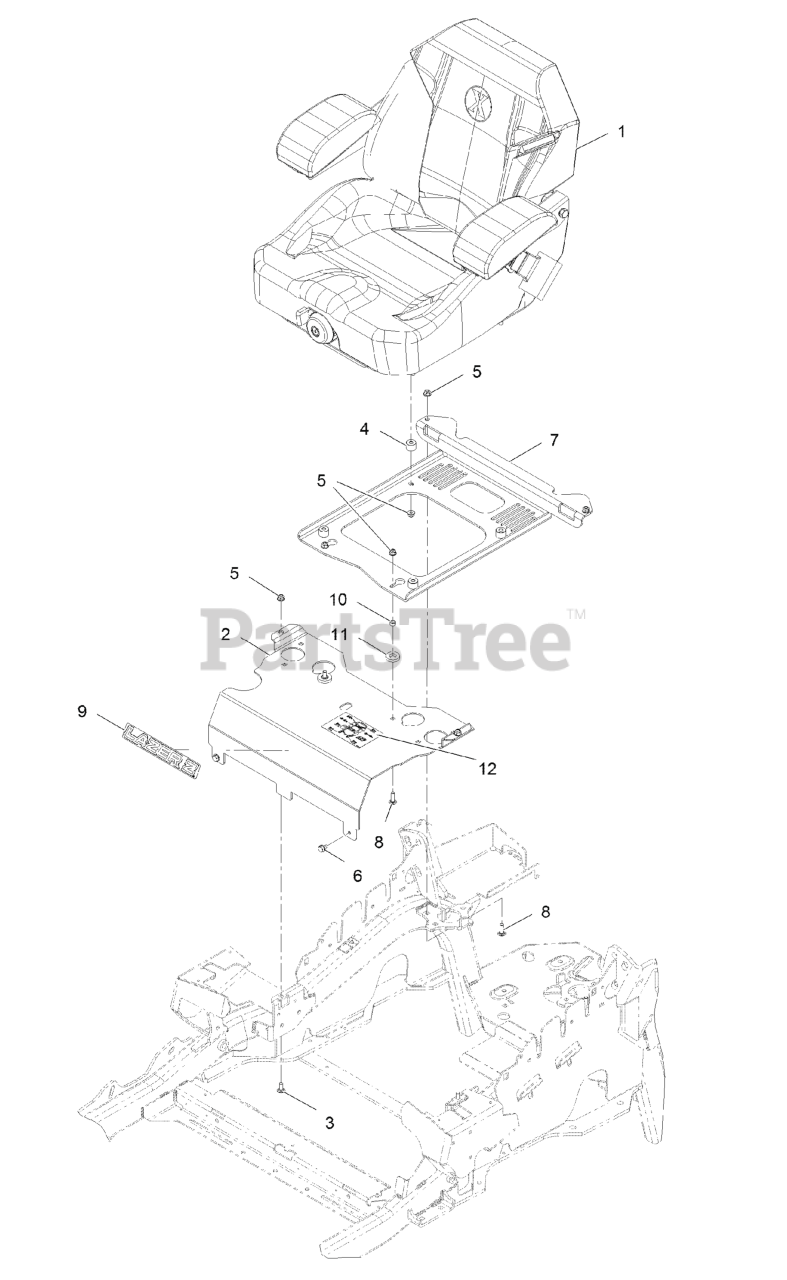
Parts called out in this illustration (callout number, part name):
1	KIT-SUSPENSION SEAT
2	Panel-Front, Seat Mount
3	SCREW-CARR
5	NUT-HF, NI
7	PLATE-SUPPORT, SEAT
8	SCREW-CARR
9	DECAL, LAZER MODEL
10	NUT-HEX
12	DECAL-SERVICE AID
